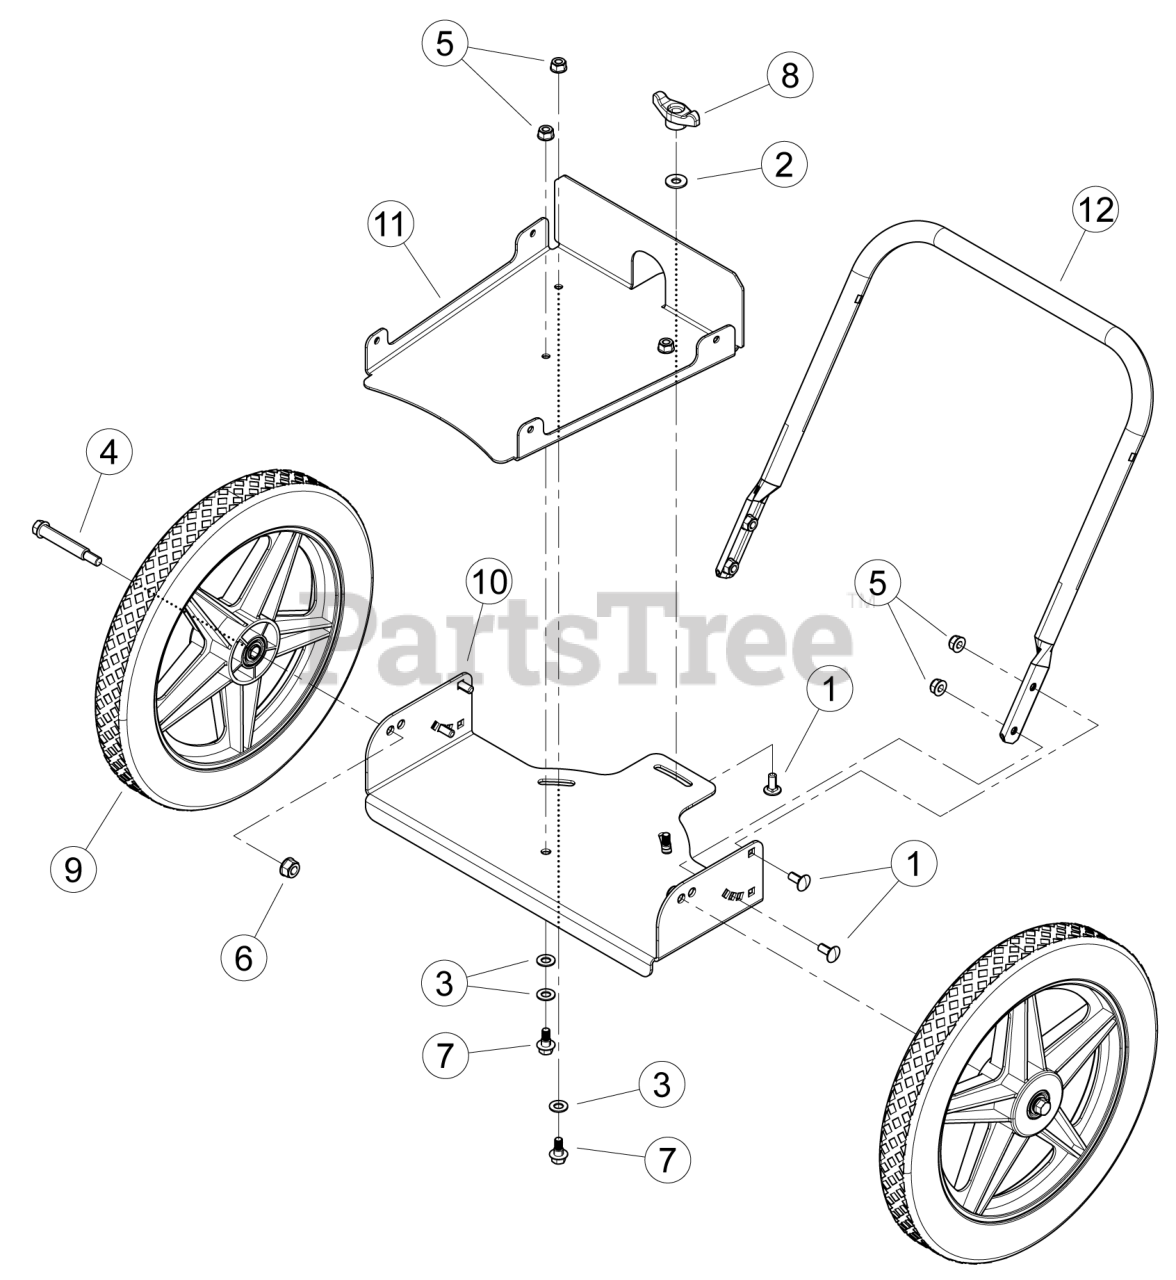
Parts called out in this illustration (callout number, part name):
1	BOLT, 5/16-18 × 3/4 SN GR5 CRG
2	WASHER, 5/16 FLAT
3	WASHER, NYLON .390 ID × .750 OD
4	BOLT, 3/8-16 × 3-1/4 FLANGED SHOULDER
5	NUT, 5/16-18 NYLOCK FLANGE
6	NUT, 3/8-16 NYLOCK FLANGE
7	BOLT, 5/16-18 × 3/4 ZP FLANGE SHOULDER
8	KNOB, 5/16-18 FEEM TEE
9	WHEEL, TRIMMER 15 × 1.75
10	PLATE, TRIMMER AXLE
11	PLATE, TRIMMER BASE PUSH
12	HANDLE BAR, LOWER TRIMMER PAINTED
